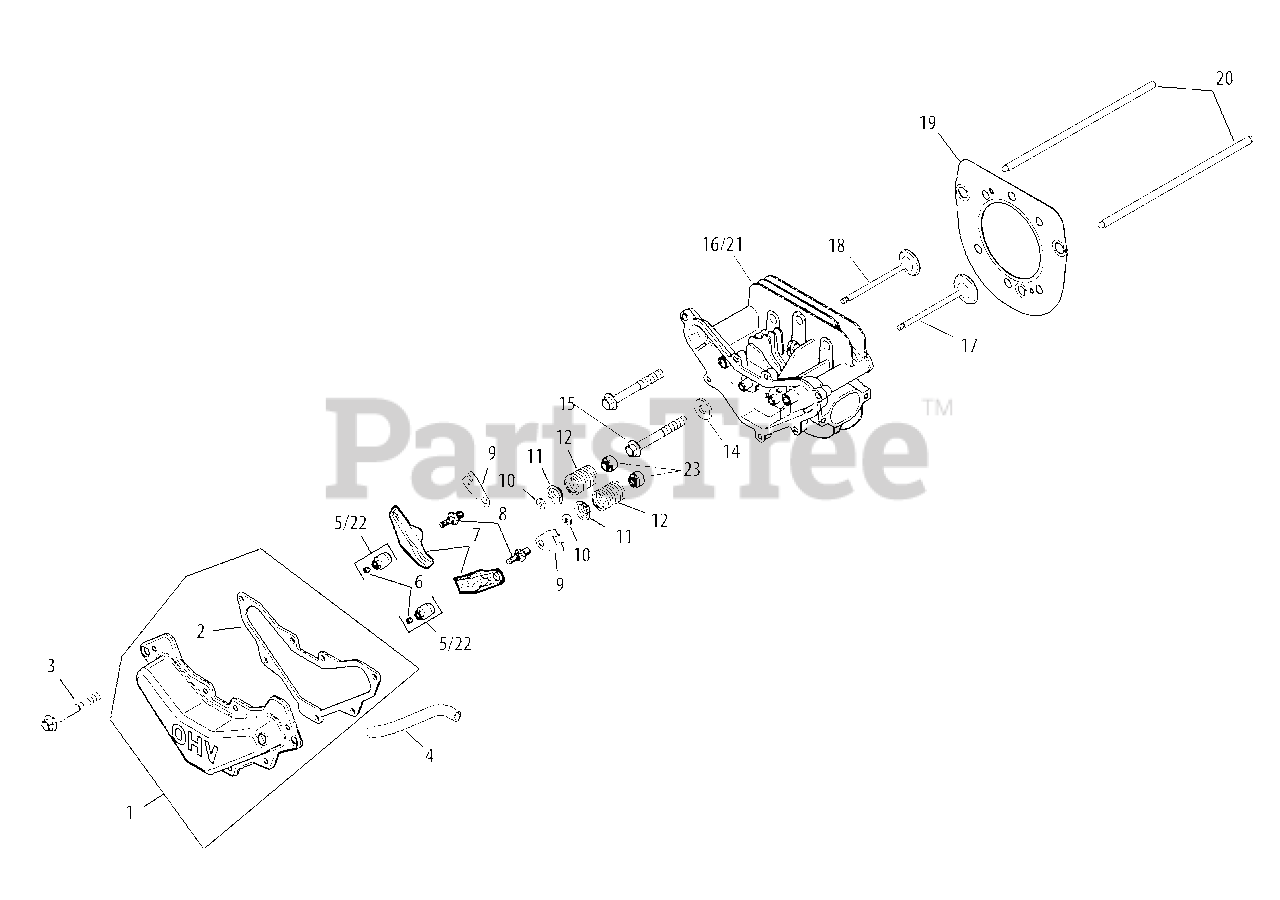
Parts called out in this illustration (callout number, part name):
1	Valve Cover Kit (Incl. 2)
2	Valve Cover Gasket
3	Flg. Screw, M6 X 1.0 X 20
4	Breather Hose
5	Rocker Pivot Assembly (Incl. 6)
9	Push Rod Guide Plate
10	Retainer Lock
11	Valve Spring Cap
14	Flat Washer, 13/32
15	Flange Screw, M10 X 1.5 X 80
17	Exhaust Valve
19	Cylinder Head Gasket Kit
21	Kit, Cylinder Head (Incl. 28 & 29)
23	Valve Stem Seal
